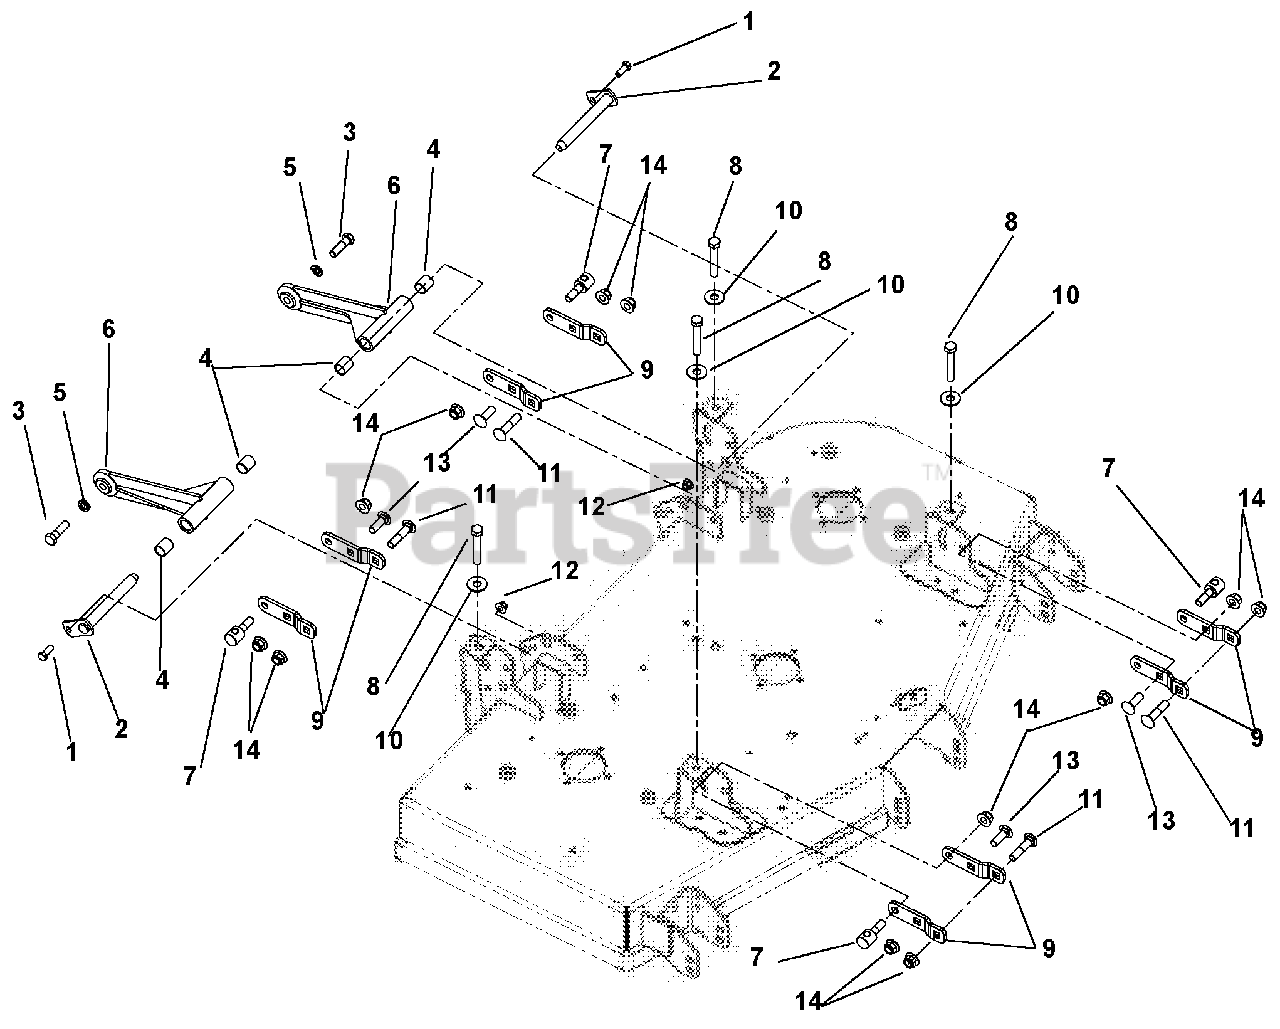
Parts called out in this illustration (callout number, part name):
1	Bolt, Hex .38-16 x 1.00
2	Weldment, Mower Mounting Pin
3	Bolt, Hex .50-13 x 1.75 Grade 5 EP80
4	Bearing, .75 x .875 x 1.00
5	Washer, Locking .50 x .125 Regular
6	Deck Pusher Arm Weldment, Black
7	Trunnion, .50-13
8	Bolt, Hex .50-13 x 3.00
9	Bracket, Deck Leveling
10	Washer, Flat Steel .563 x 1.38 x .109
11	Bolt, Round Head Square Neck .50-13 x 2.25
12	Nut, Locking Nylon Flange .38-16
13	Bolt, Round Head Square Neck .50-13 x 1.50
14	Nut, Locking Nylon Flange .50-13
